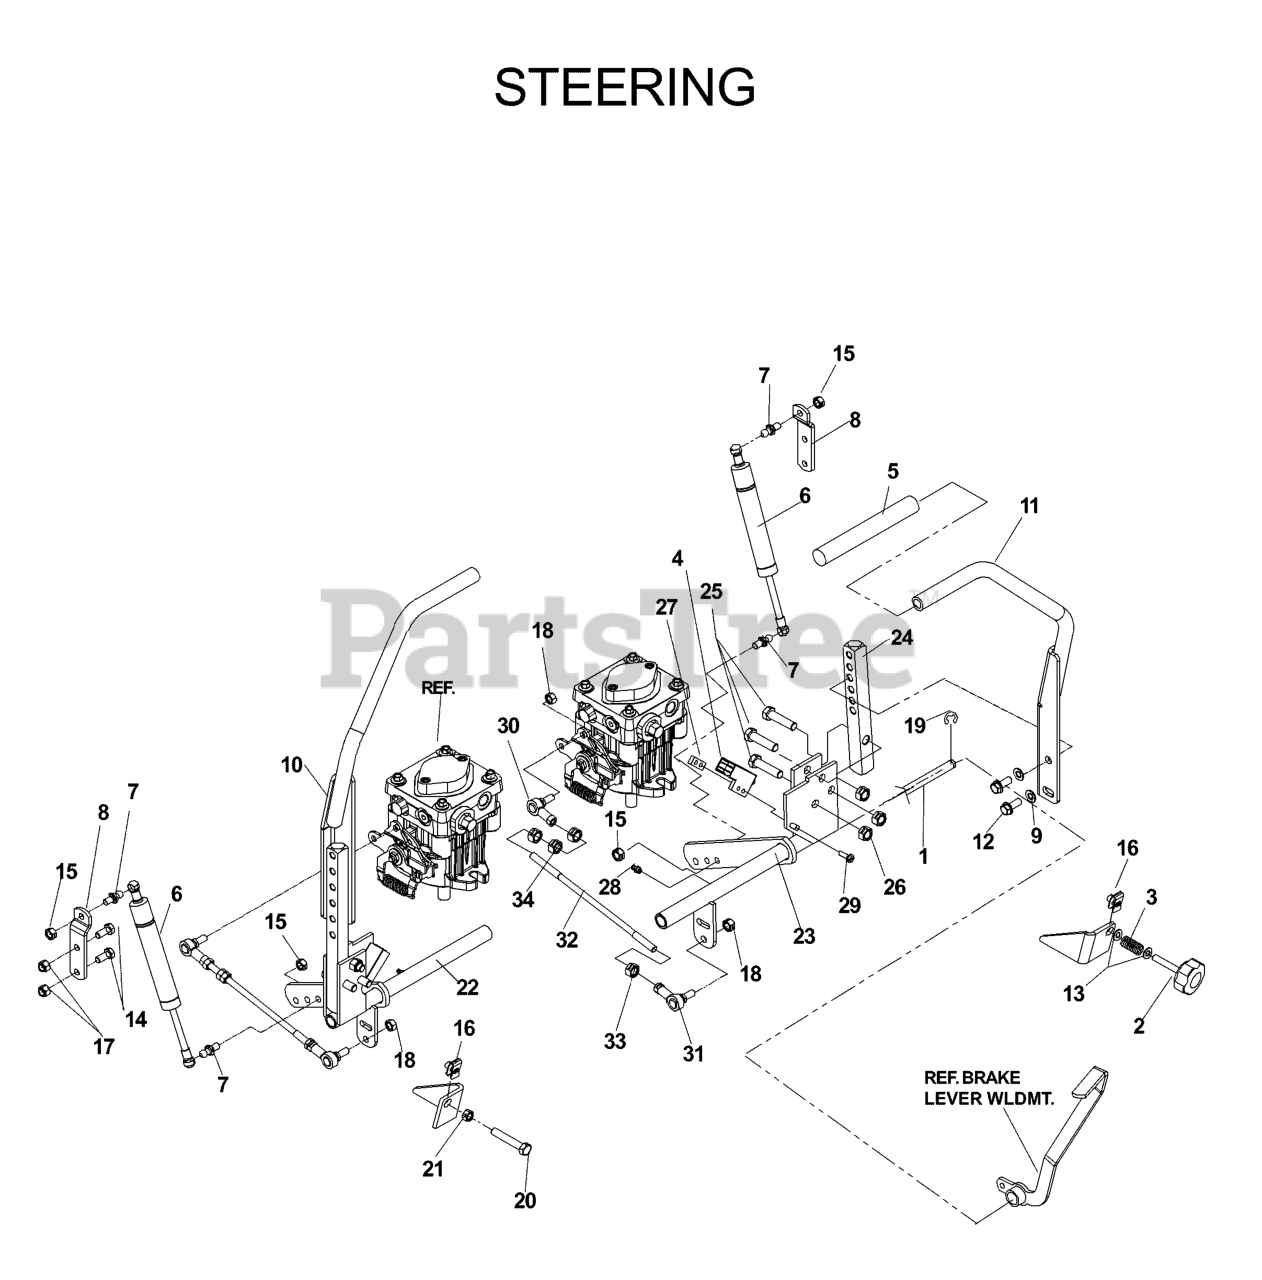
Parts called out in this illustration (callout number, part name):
1	CONTROL SHAFT
2	ADJUSTMENT KNOB
3	COMPRESSION SPRING
4	SWITCH, INTERLOCK
6	DAMPENER
7	STUD.BALL.10MM
8	DAMPENER ARM
9	WASHER, 3/8 DISC SPRING SPEC
10	RT DRIVE LEVER WLDMT
11	LT DRIVE LEVER WLDMT
12	HCS 3/8-16X1.GRD.5.ZD
13	WASHER 5/16 FLAT
14	HCS 5/16C X 3/4
15	NUT 5/16C CENTERLOCK
16	U-CLIP 5/16-18 NUT RETAINER
17	NUT 5/16 NYLOC
18	NUT 5/16F NYLOC
19	E-RING 1/2 (2 2)
20	HCS 5/16-18X1-3/4 TPBLT
21	NUT 5/16C HEX
22	DRIVE CONTROL, RT
23	DRIVE CONTROL, LT
24	CONTROL ARM
25	HCS 3/8-16 X 1 3/4 GR5
26	NUT 3/8-16 NYLOC
27	TAPPED PLATE
28	ZERK
29	SCREW #10-24 X 5/8
30	SPHERICAL ROD END, RH
31	SPHERICAL ROD END, LH
32	PUMP CONTROL LINK
33	NUT 5/16F LEFTHAND
